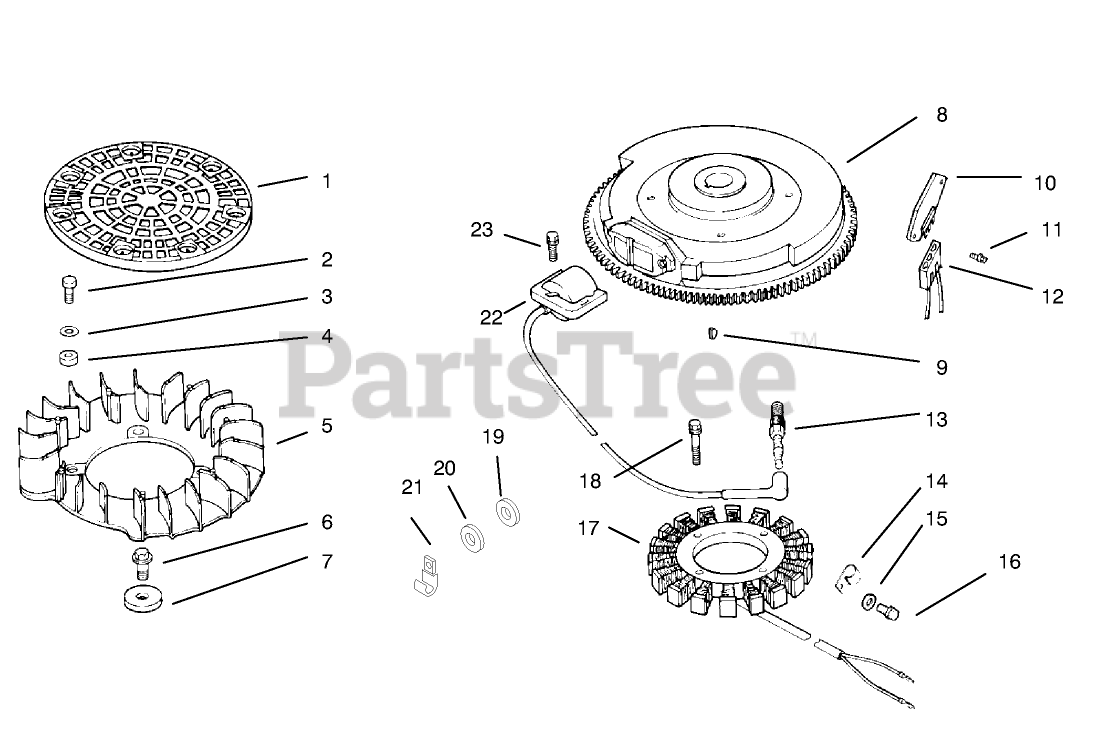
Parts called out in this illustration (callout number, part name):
1	Screen-Grass (Only On: 72103, 72083)
2	Screw-Hex.
3	Washer
4	Spacer-Fan (Only On: 72103)
5	Fan (Only On: 72103, 72083)
7	Spacer-Fan
8	Flywheel ASM (Only On: 72103, 72083)
10	Rectifier-Regulator
12	Connector
13	Spark Plug
16	Screw
17	Stator-15 amp
19	Washer
20	Washer
22	Module-Ignition
